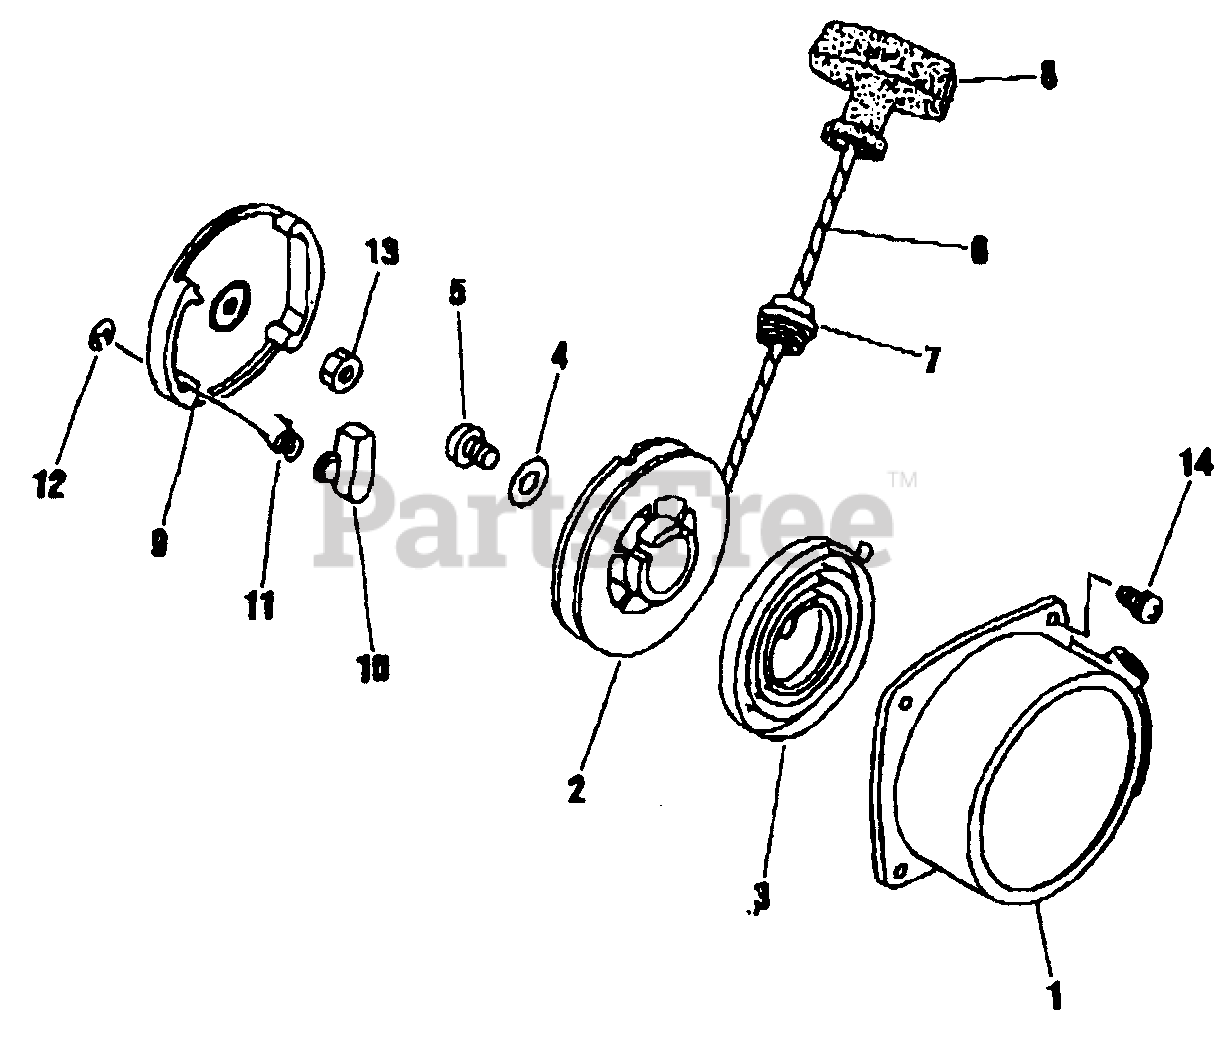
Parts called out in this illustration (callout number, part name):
1	CASE, STARTER
2	REEL, ROPE
3	SPRING, RECOIL
4	WASHER 5
5	SCREW
7	GUIDE, ROPE
8	GRIP, STARTER
9	PULLEY
10	RATCHET
11	SPRING, RETURN
12	E-RING
13	NUT
14	SCREW
